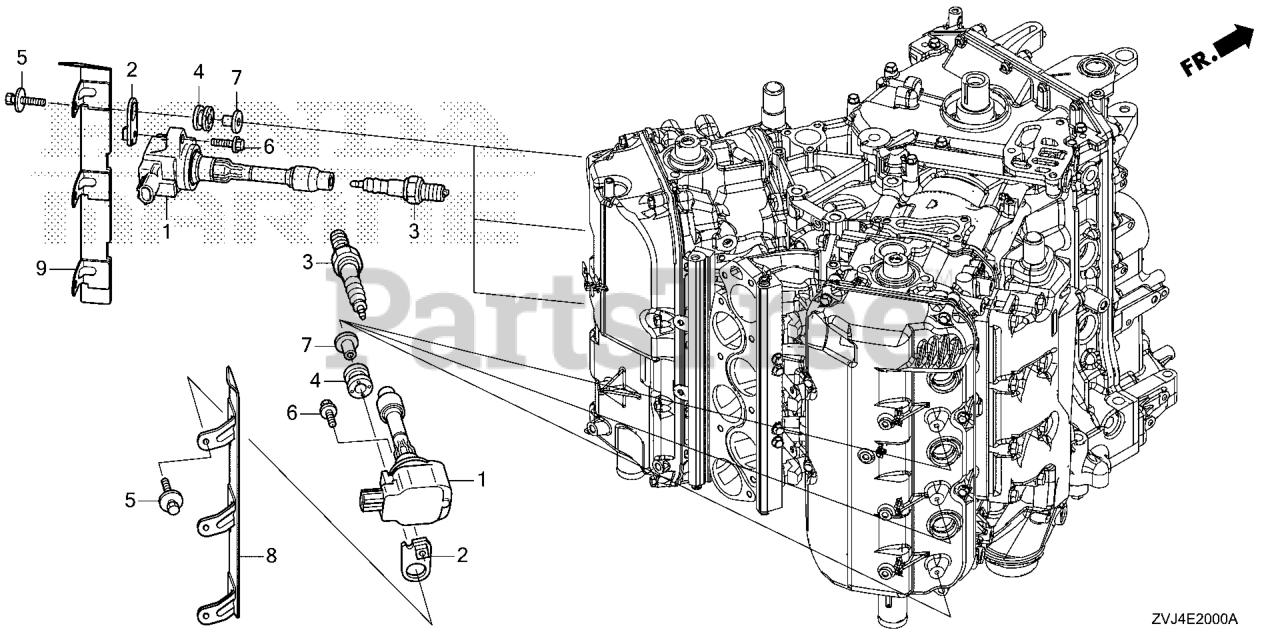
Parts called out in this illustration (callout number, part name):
1	COIL ASSY., PLUG TOP
2	STAY, PLUG TOP COIL
3	SPARK PLUG (ZFR6K-11E) (NGK)
3	SPARK PLUG (IZFR6K-11E) (NGK)
4	GROMMET, RELAY BRACKET
5	BOLT-WASHER (6X27)
6	BOLT, FLANGE (6X20)
7	COLLAR, MODULE IGNITION CONTROL CASE (CDI)
7	COLLAR (12X6.5)
8	GUARD R, PTC SIDE
9	GUARD L, PTC SIDE
